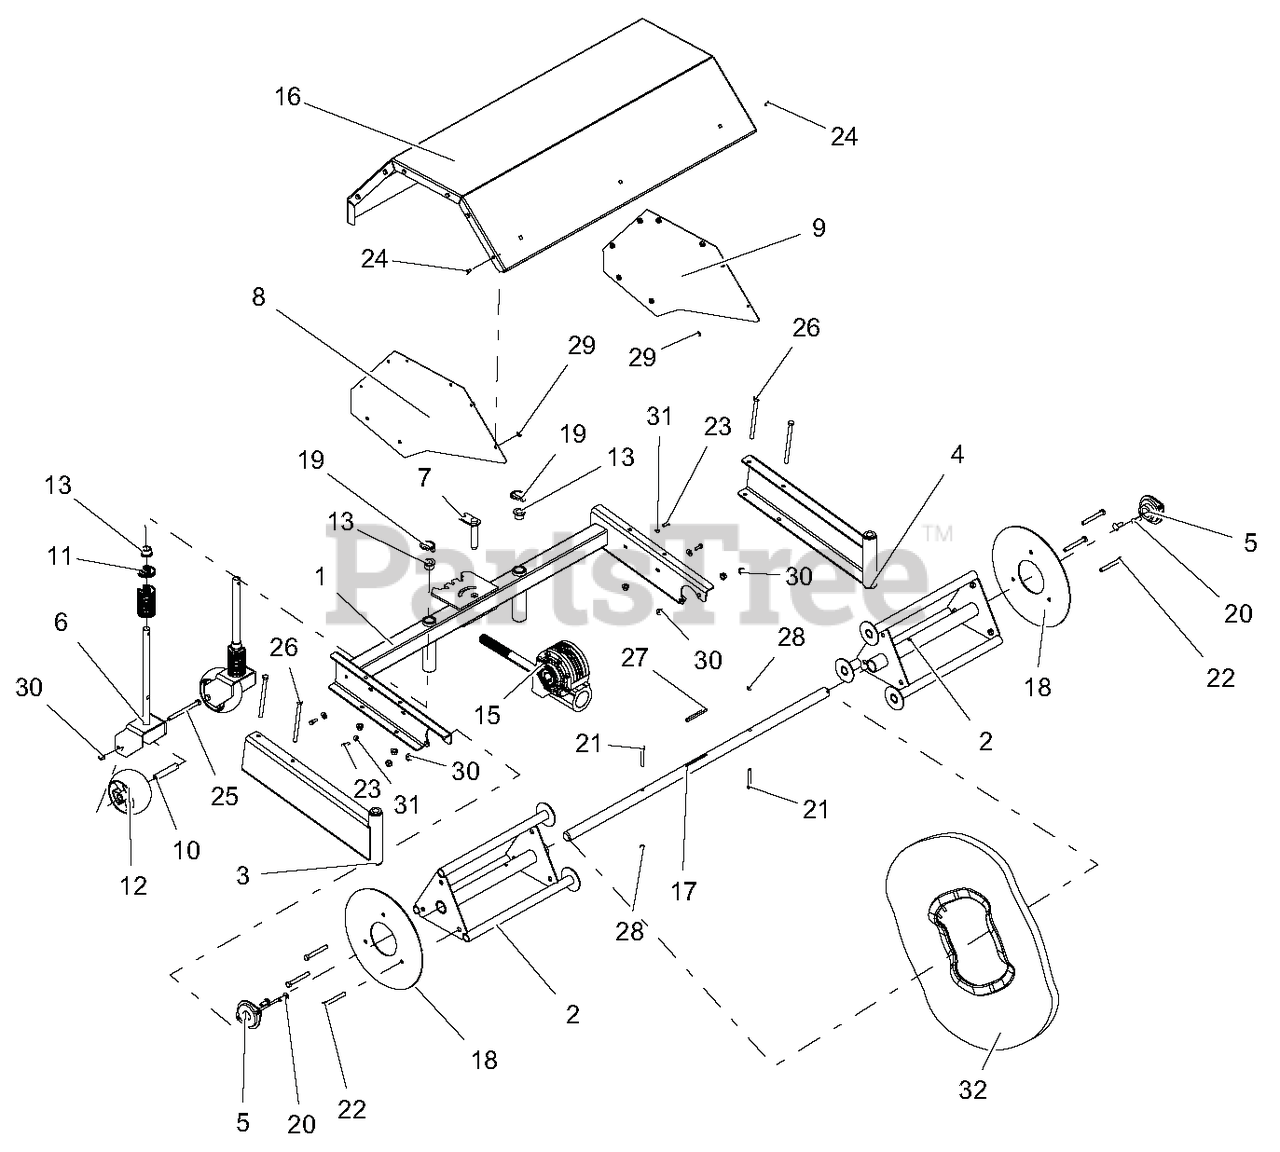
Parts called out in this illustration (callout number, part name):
1	FRAME, POWER BROOM 36"
2	PB36 DRIVE CORE SERVICE KIT
3	CASTER, ARM WELDMENT RH
4	CASTER, ARM WELDMENT LH
5	BEARING,2 BOLT FLANGE 1-1/8 ID
6	FORK, CASTER
7	WLDMT, BRUSH PIN
8	WLDT - SIDE COVER RH
9	WLDT - SIDE COVER LH
10	SPACER, CASTER WHEEL
11	CLIP-HOC FIXED
12	ANTI-SCALP WHEEL - 5X3 CTR
13	BUSHING, FLANGE .75X.75X1.0
15	GEARBOX, WORM - 8.25:1
16	COVER,TOP - 36"BRUSH W/DECALS
17	CENTER, SHAFT
18	PLATE, END RETAINER
19	PIN, 1/4X1-9/16 LYNCH
20	@BLT-RDHDSQNK .38-16X1.00 G5YZ
21	@BLT-HEX .31-18X2.25 GR5 YWZC
22	BLT-HEX .38-16X3.00 GR5 FTH YZ
23	@BLT-HEX .25-20X.75 GR5 YWZC
24	@BLT-HEX .25-20X.50 GR5 YWZC
25	@BLT-HEX .38-16X4.50 GR5 YWZC
26	@BLT-HEX .38-16X5.50 GR5 YWZC
27	KEY .25 X .25 X 3IN
28	@NUT-LK-CTR .31-18 YWZC
29	@NUT-LK-TOP-FLG .25-20 YWZC
30	@NUT-LK-TOP-FLG .38-16 YWZC
31	@WSHR-FL-STL.312X.734X.065 YWZ
32	KIT, BRISTLE - SET OF 18
